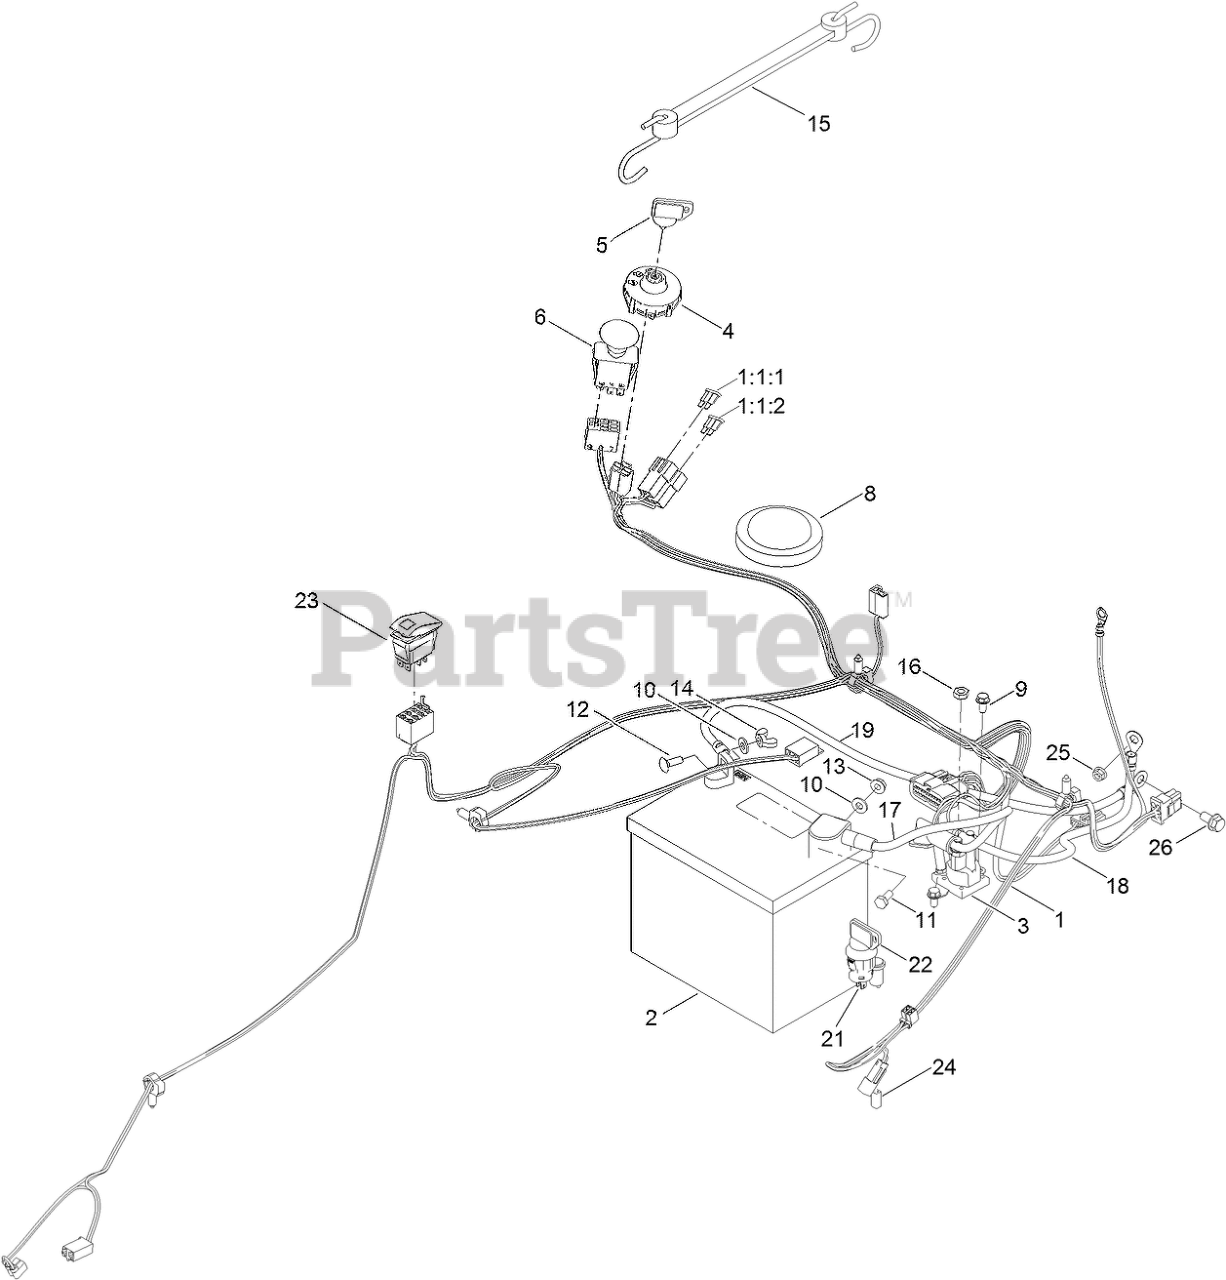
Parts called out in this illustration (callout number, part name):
1	HARNESS-WIRE
1:1	HARNESS-WIRE
1:1:1	FUSE-BLADE, 30 AMP
1:1:2	FUSE-BLADE, 25 AMP
2	BATTERY
3	SOLENOID
4	SWITCH-IGNITION
5	KEY-IGNITION
6	SWITCH-PTO, ON-ON
8	SWITCH-SEAT
9	SCREW-HWH
10	WASHER-FLAT
11	SCREW-HH
12	BOLT-CARR
13	NUT-HF
14	NUT-WING
15	HOLDDOWN-BATTERY
16	NUT-JAM
17	CABLE-BATTERY, RED
18	CABLE-BATTERY, POSITIVE
19	CABLE-BATTERY, BLACK
21	SWITCH-MOMENTARY, N.O.
22	KEY-TORO
23	SWITCH-ROCKER, (ON)-OFF-(ON)
24	LIGHT-INDICATOR
25	NUT-HF
26	SCREW-HHF
